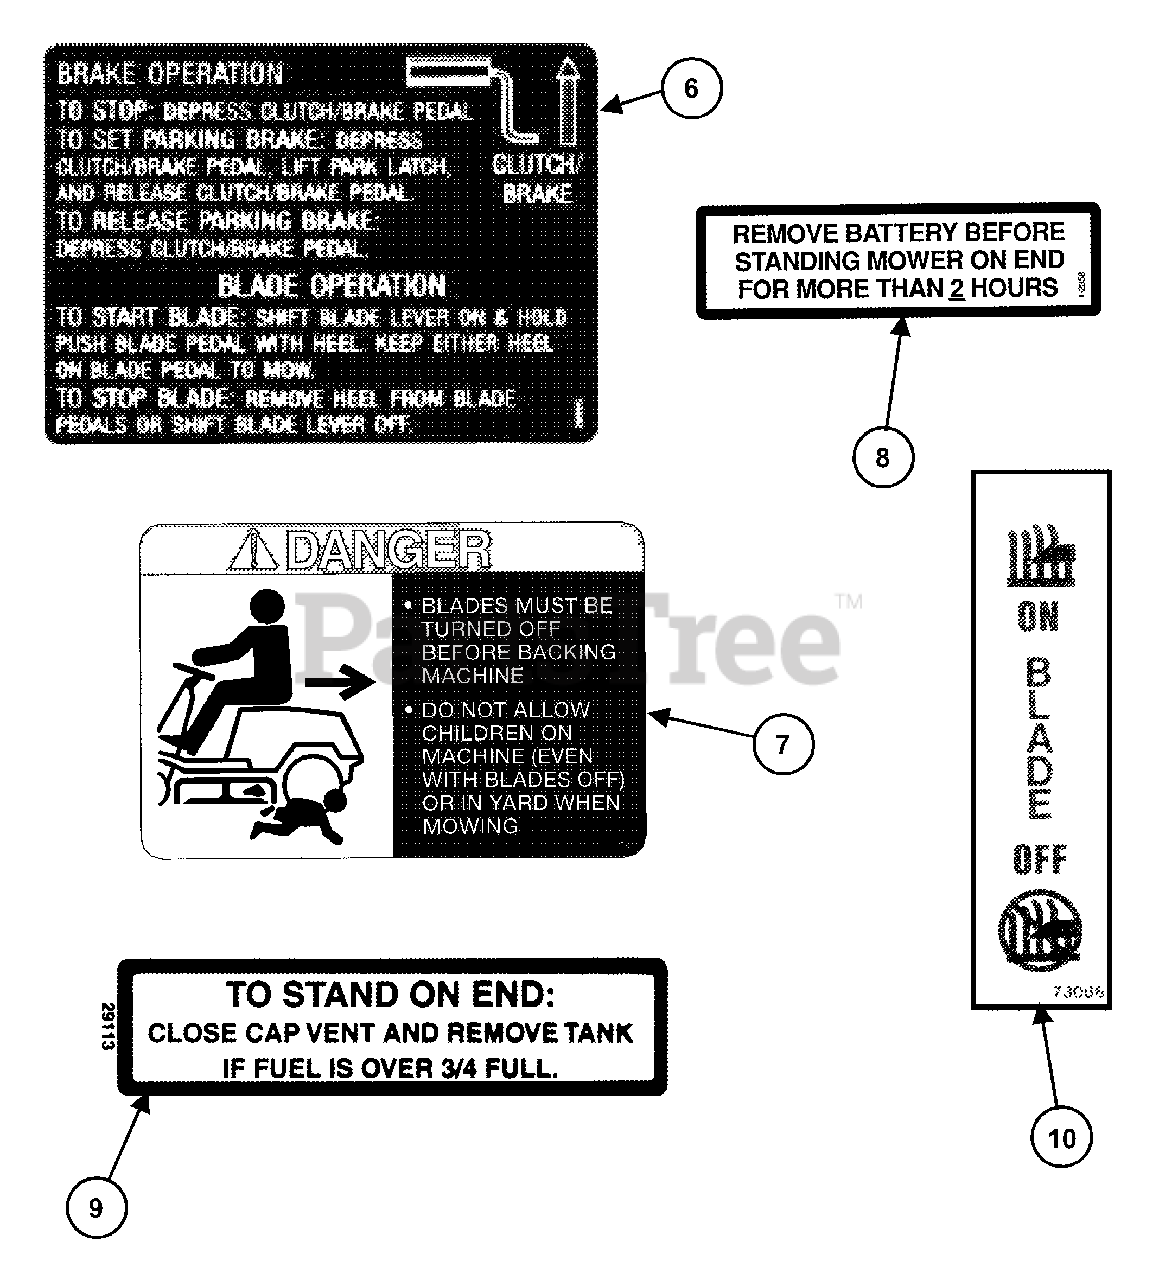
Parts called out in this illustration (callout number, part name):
6	DECAL, Brake/Blade Operation
7	DECAL, No Mow in Reverse
8	DECAL, Battery Storage
9	DECAL, Caution, Fuel
10	DECAL, Blade Engagement (42")
